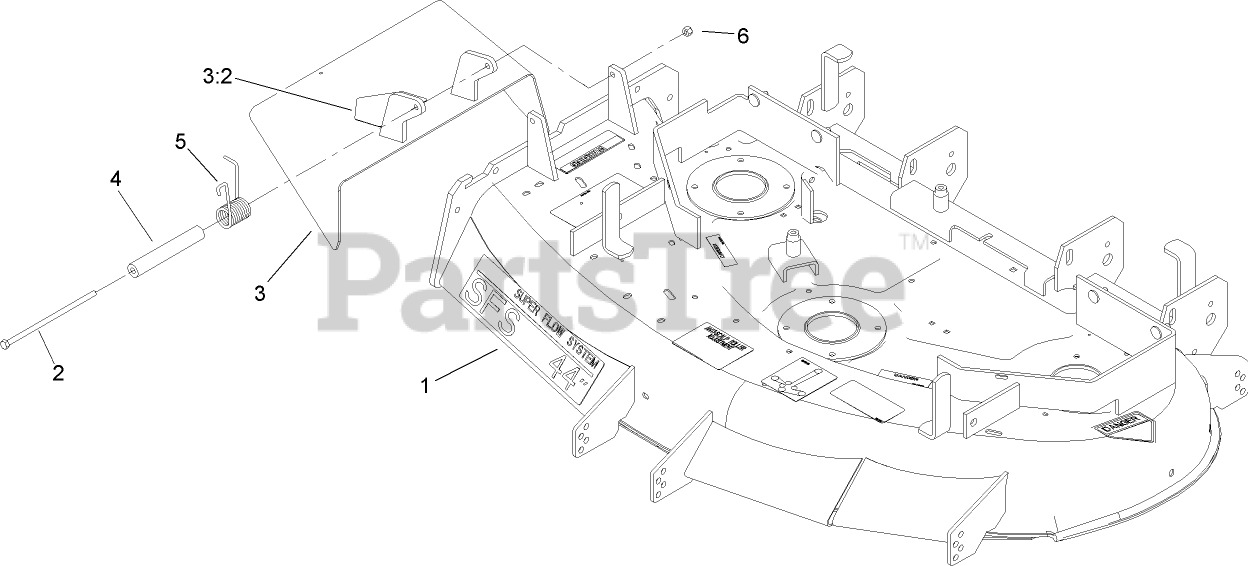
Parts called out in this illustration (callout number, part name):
1	DECK DECAL ASM
2	SCREW-HH
3	Deflector ASM
3:2	DECAL-DANGER
4	SPACER
5	SPRING-TORSION
6	NUT-LOCK, NI
